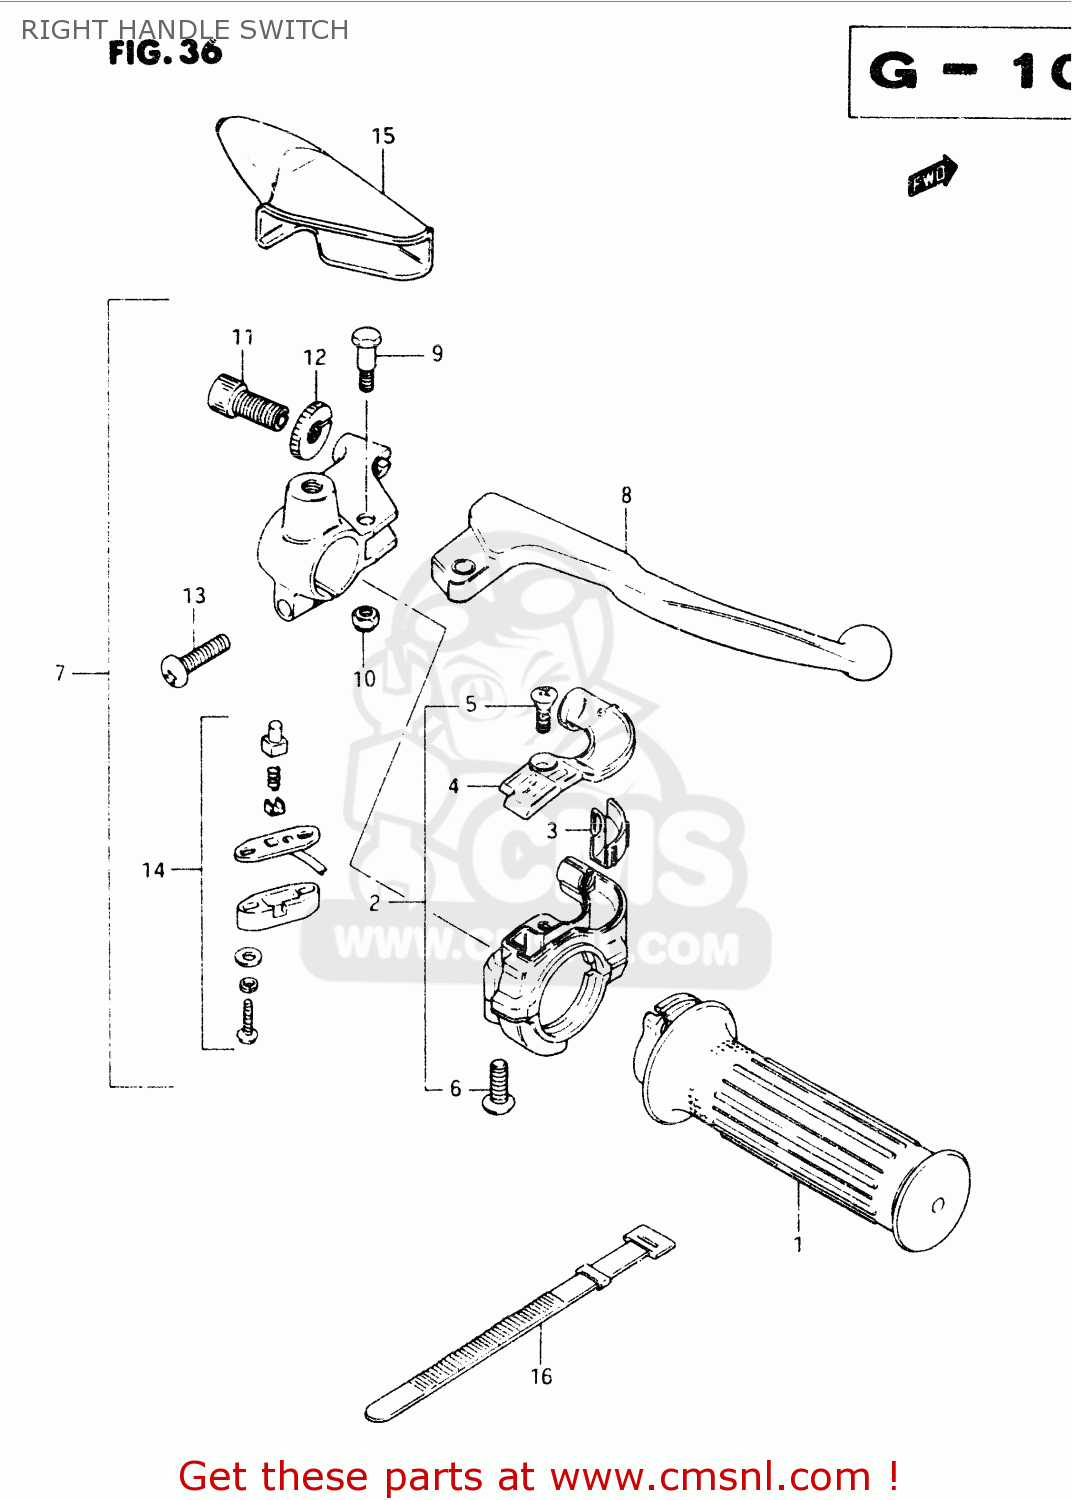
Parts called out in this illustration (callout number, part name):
1	GRIP,THROTTLE
2	CASE ASSY,THROTTLE
3	GUIDE PIECE,THROTTLE
4	COVER,THROTTLE CASE
5	SCREW 4X10
6	SCREW
7	BRAKE LEVER & SWITCH ASSY
8	LEVER,BRAKE
9	BOLT,LEVER PIVOT
10	NUT 6MM
11	ADJUSTER,CABLE
12	NUT,CABLE ADJUSTER
13	SCREW
14	SWITCH ASSY,STOP
15	DUST SEAL,BRAKE/CLUTCH
16	CLAMP(L:120)
